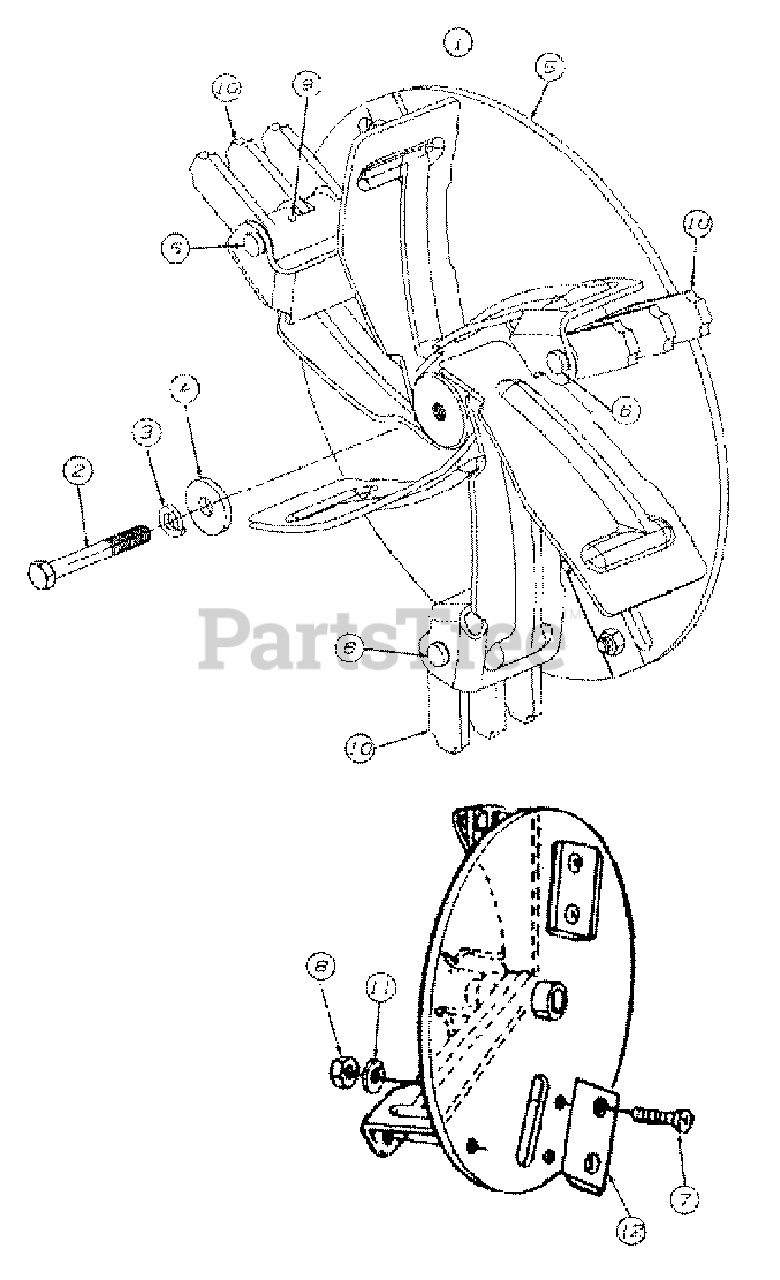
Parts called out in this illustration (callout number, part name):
1	IMPELLER ASS'Y COMP.
2	SCREW-HEX
3	WASHER-LOCK
4	WASHER-FLAT
5	IMPELLER ASSY
6	PIN-CLEVIS
7	SCREW-FLAT HEAD
8	NUT-HEX LOCK
9	PIN-ROLL SPRING
10	BLADE-FLAIL
11	WASHER-LOCK
12	BLADE-CHIPPER - PREMIUM
